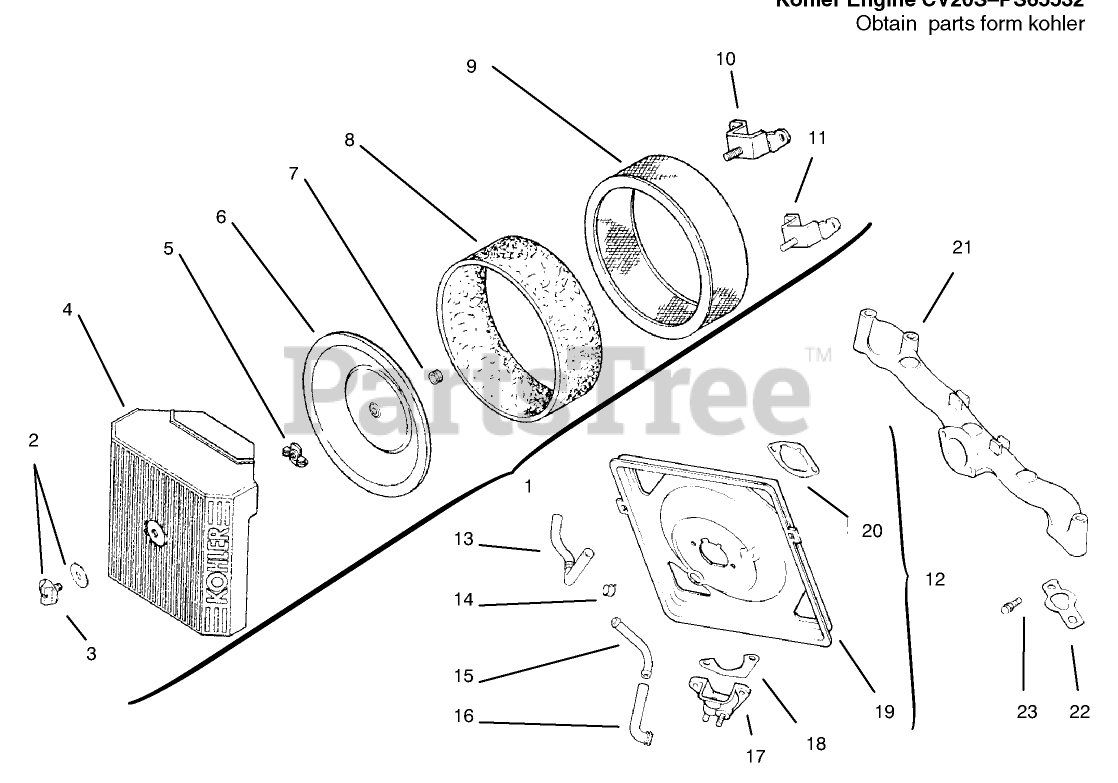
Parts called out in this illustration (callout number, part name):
1	Kit-A/C Cover INCL 2-4 (Only On: 72103;
2	Spring-Latch (Only On: 72103)
3	Latch-Lever (Only On: 72103)
4	Pin-Latch Lever (Only On: 72103)
5	Nut-Wing
6	Seal-Air Intake (Only On: 72103)
7	Cover-Inner Air Cleaner
8	Element-Precleaner
9	Element-Air Cleaner
10	Cup-Fuel Spitback (Only On: 72103)
11	Gasket-Fuel Spitback Cup (Only On: 72103, 72083)
12	Base-Air Cleaner (Only On: 72103)
13	Gasket-A/C Base (Only On: 72103, 72083)
14	Manifold-Intake (Only On: 72103)
15	Gasket-Intake Manifold
